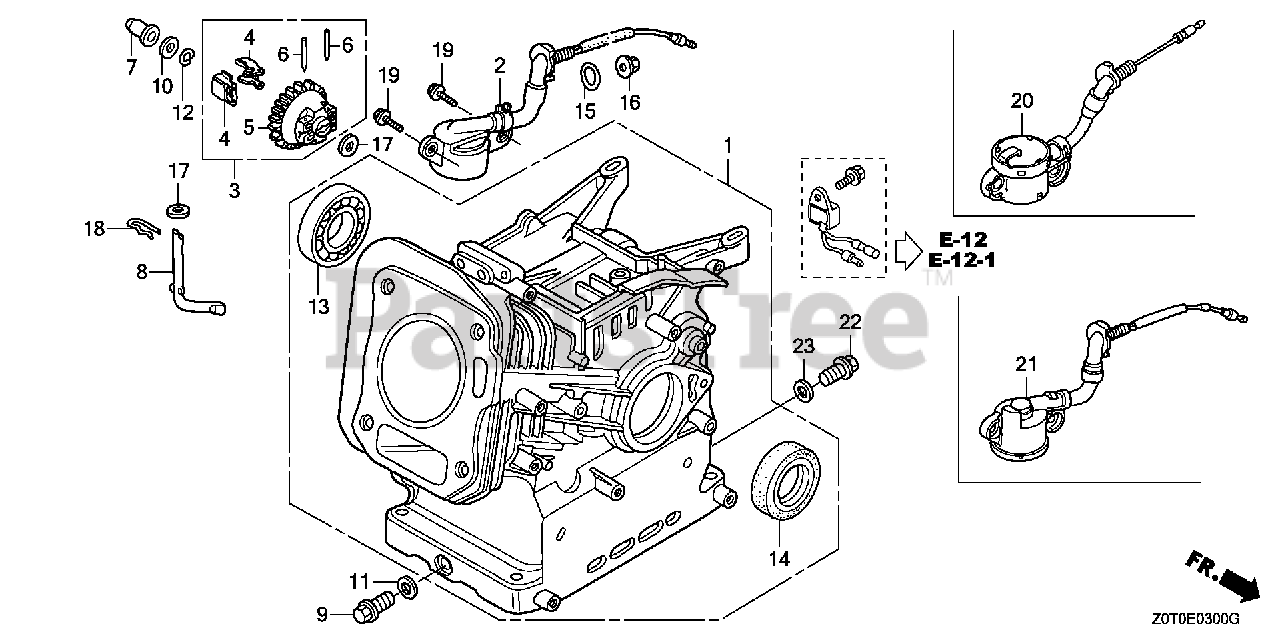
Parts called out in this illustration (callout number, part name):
1	CYLINDER ASSY. (OIL ALERT)
2	SWITCH ASSY., OIL LEVEL
3	GOVERNOR ASSY.
7	SLIDER, GOVERNOR
8	SHAFT, GOVERNOR ARM
9	BOLT, DRAIN PLUG
10	WASHER, THRUST (6MM)
11	WASHER, DRAIN PLUG (10.2MM)
12	CLIP, GOVERNOR HOLDER
13	BEARING, RADIAL BALL (6205TMB) (NTN)
14	OIL SEAL (25X41X6) (NOK)
15	O-RING (13.5X1.5) (ARAI)
15	O-RING (14MM) (NOK)
16	NUT, FLANGE (10MM)
17	WASHER, PLAIN (6MM)
18	PIN, LOCK (8MM)
19	BOLT, FLANGE (6X12)
22	BOLT, DRAIN PLUG
23	WASHER, DRAIN PLUG (10.2MM)
